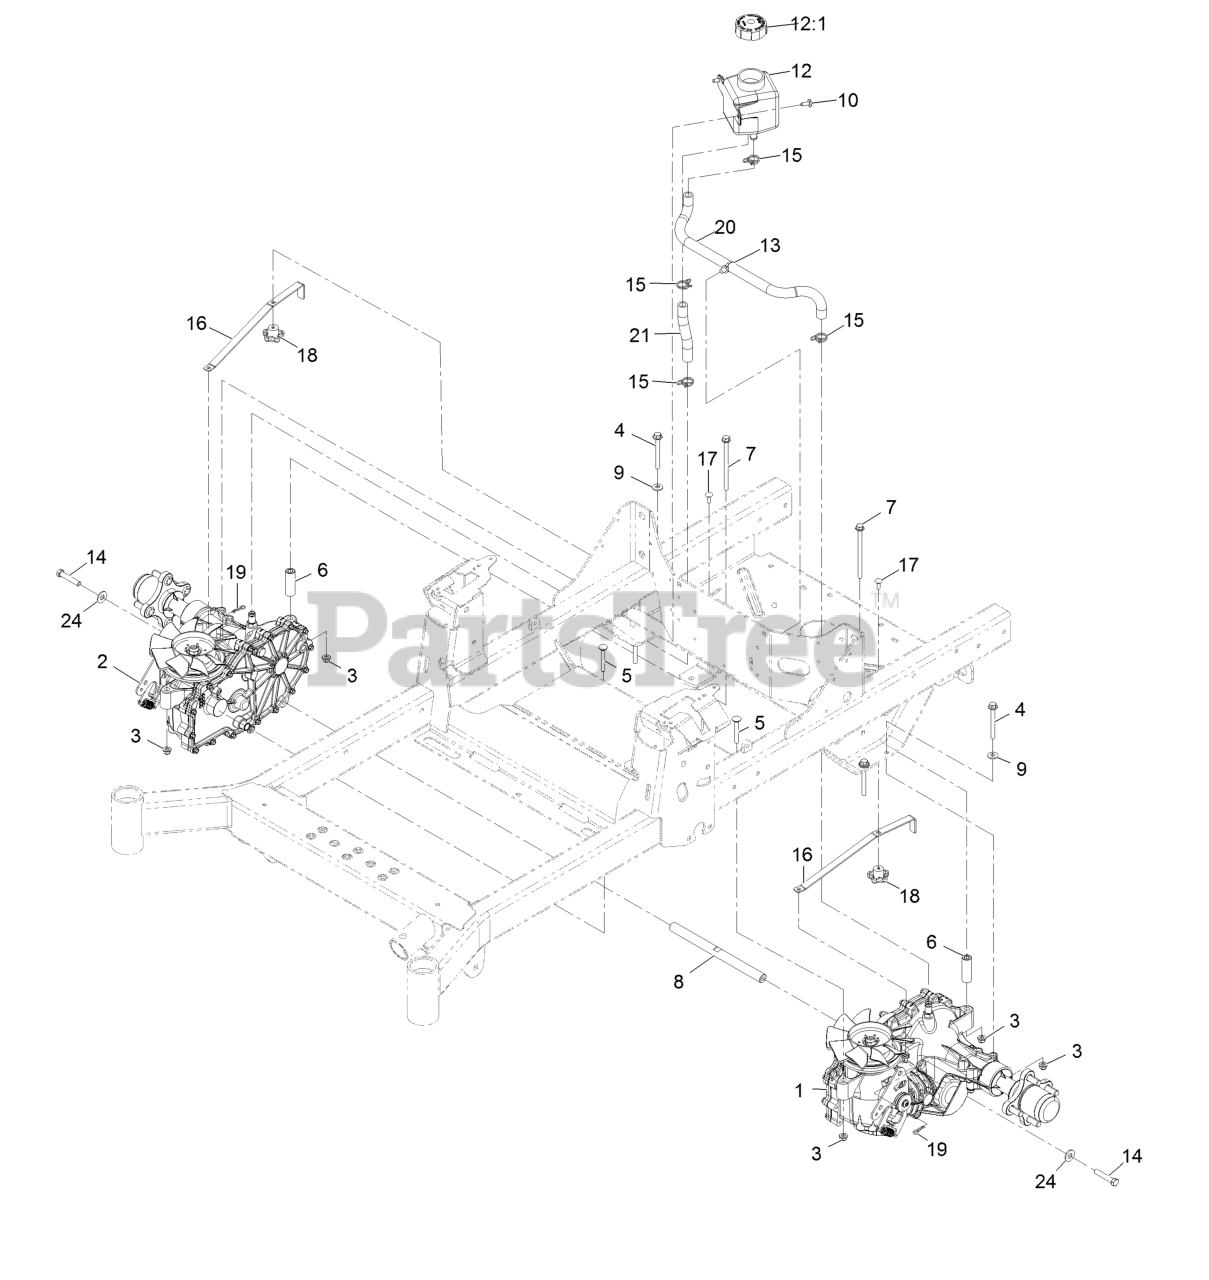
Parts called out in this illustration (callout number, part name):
1	Transaxle ASM LH
2	Transaxle ASM RH
3	Nut-Nyloc 5/16-18 Flg
4	Screw-HHF
5	Bolt-Carriage 5/16-18 X 2 1/4
6	Spacer-Hydro
7	Screw HHF
8	Shaft-Spacer
9	Washer-Spring Disc 5/16
10	Screw-1/4-20 X .65 Torx Plus
12	Tank-HYD
12:1	Cap-Reservoir, HYD
13	Clip-Tie
14	Screw-HH W/Loctite
15	Clamp-Hose
16	Arm-Bypass, Hydro
17	Bolt-Carriage 1/4-20 X 3/
18	Knob-Handle
19	Hairpin-Cotter
20	Hose-Hydraulic
21	Hose-Hydraulic
24	Washer-3/8 Std
